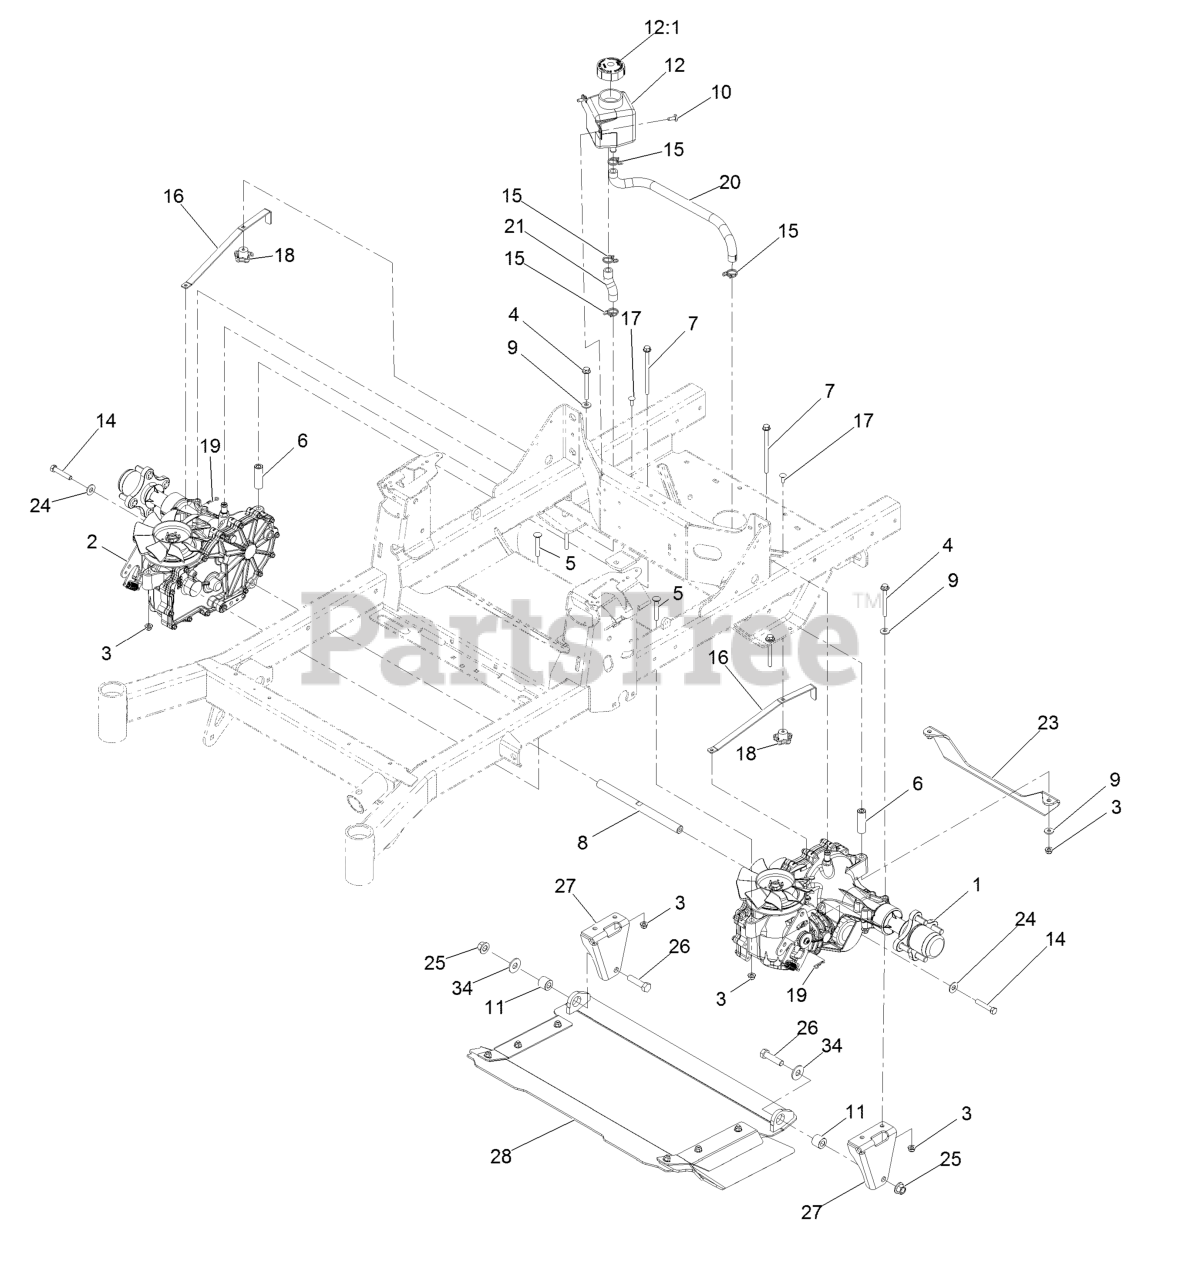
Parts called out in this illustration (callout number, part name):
1	LH Transaxle ASM
2	RH Transaxle ASM
3	Nut-Nyloc 5/16-18 Flg
4	Screw-HHF
5	Bolt-Carriage 5/16-18 X 2 1/4
6	Spacer-Hydro
7	Screw HHF
8	Shaft-Spacer
9	Washer-Spring Disc 5/16
10	Screw-1/4-20 X .65 Torx Plus
11	Bushing-Sleeve
12	Tank-HYD
12:1	Cap-Reservoir, HYD
14	Screw-HH W/Loctite
15	Clamp-Hose
16	Arm-Bypass, Hydro
17	Bolt-Carriage 1/4-20 X 3/4
18	Knob-Handle
19	Hairpin-Cotter
20	Hose-Hydraulic
21	Hose-Hydraulic
23	Support-Transmission
24	Washer-3/8 Std
25	Nut-Lock 1/2-13
26	Screw-HH 1/2-13 X 1 1/4
27	Bracket-Mount, Discharge
28	Discharge Tunnel ASM
34	Washer
